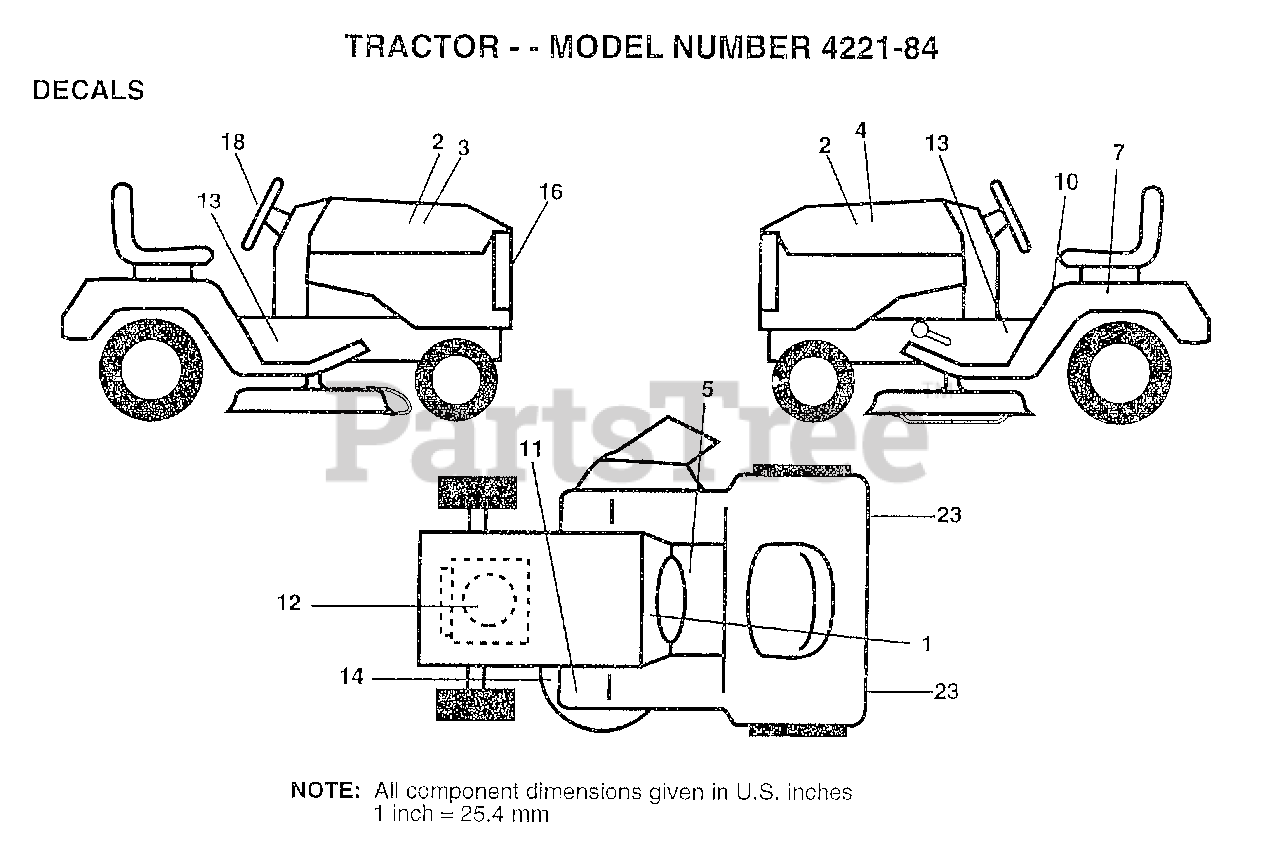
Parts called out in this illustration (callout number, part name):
1	"DECAL-INST,OPER"
2	NAMEPLATE LOGO
3	"DECAL HOOD,RH"
4	"DECAL.HOOD,LH"
5	DECAL BRAK PARK
7	DECAL.BATRY.3-3908
10	"DECAL DANGER,FEND"
12	DECAL/D-BAR CTRL MVT HYD YT/GT
13	DECAL CHASSIS
16	GRILL DECAL
23	REFLECTOR-TAIL YT
